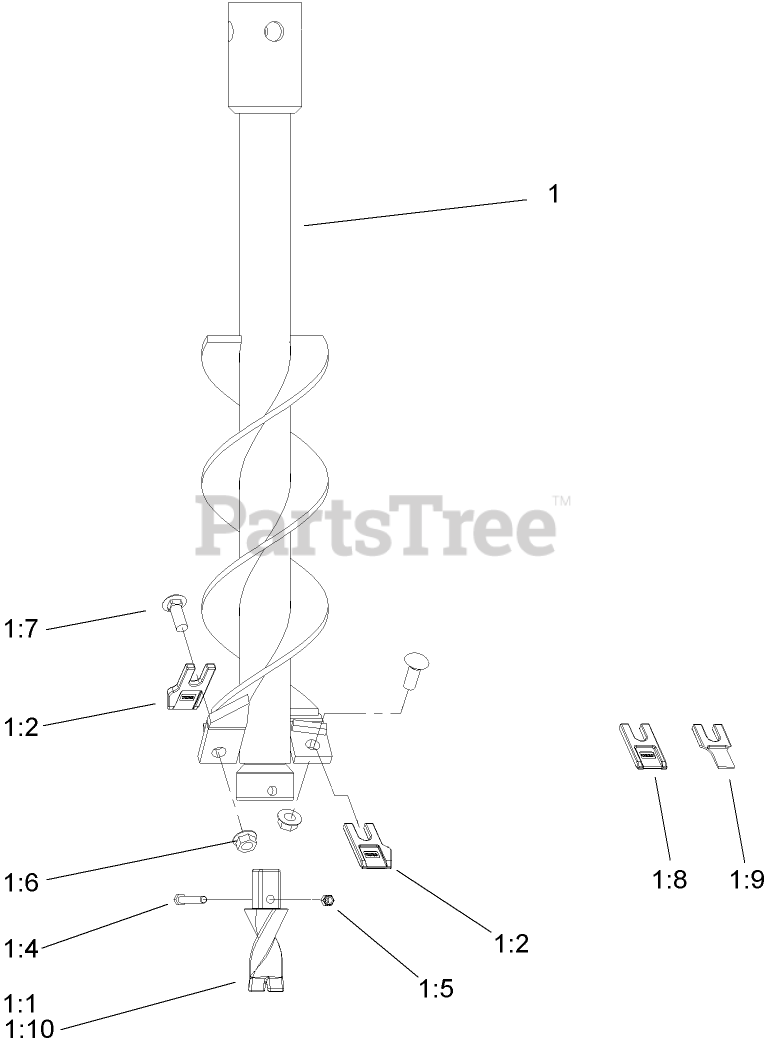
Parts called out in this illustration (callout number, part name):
1	AUGER-6 Inch
1:1	FISHTAIL-SHANK, SQUARE
1:2	TOOTH-AUGER, GAGE
1:4	SCREW-HH
1:5	NUT-LOCK, NI
1:6	SCREW-CARR
1:7	NUT-LOCK, NI
1:8	TOOTH-WISDOM, CARBIDE
1:9	TOOTH-CHISEL, CARBIDE
1:10	PILOT-HARDFACED
